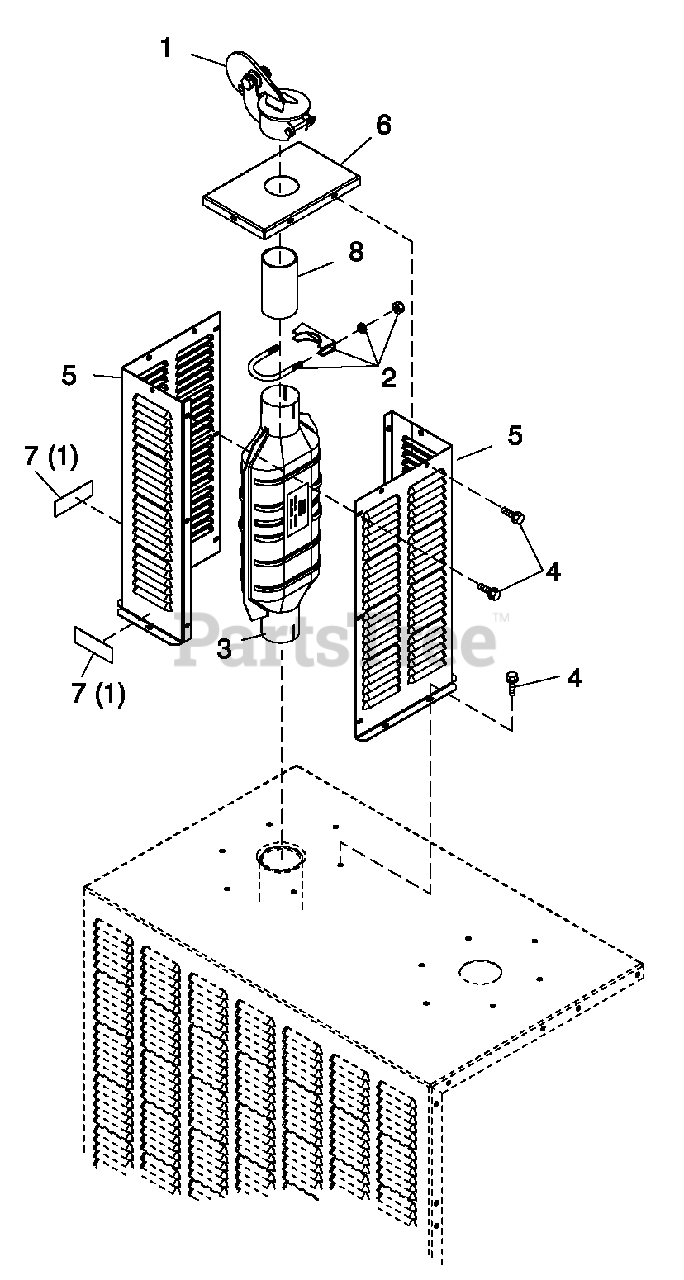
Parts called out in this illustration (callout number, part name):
1	RAIN CAP 2-1/2" AL
2	BOLT U 3/8-16X2.62
3	CATALYST 3-WAY
4	SCREW THF M6-1X16 N WA Z/JS
5	HEAT SHIELD EXHAUST STACK
6	CAP HEAT SHIELD EXHAUST STACK
7	DECAL WARNING HOT SURFACES BI
8	EMISS EXH OUTLET PIPE CPL
